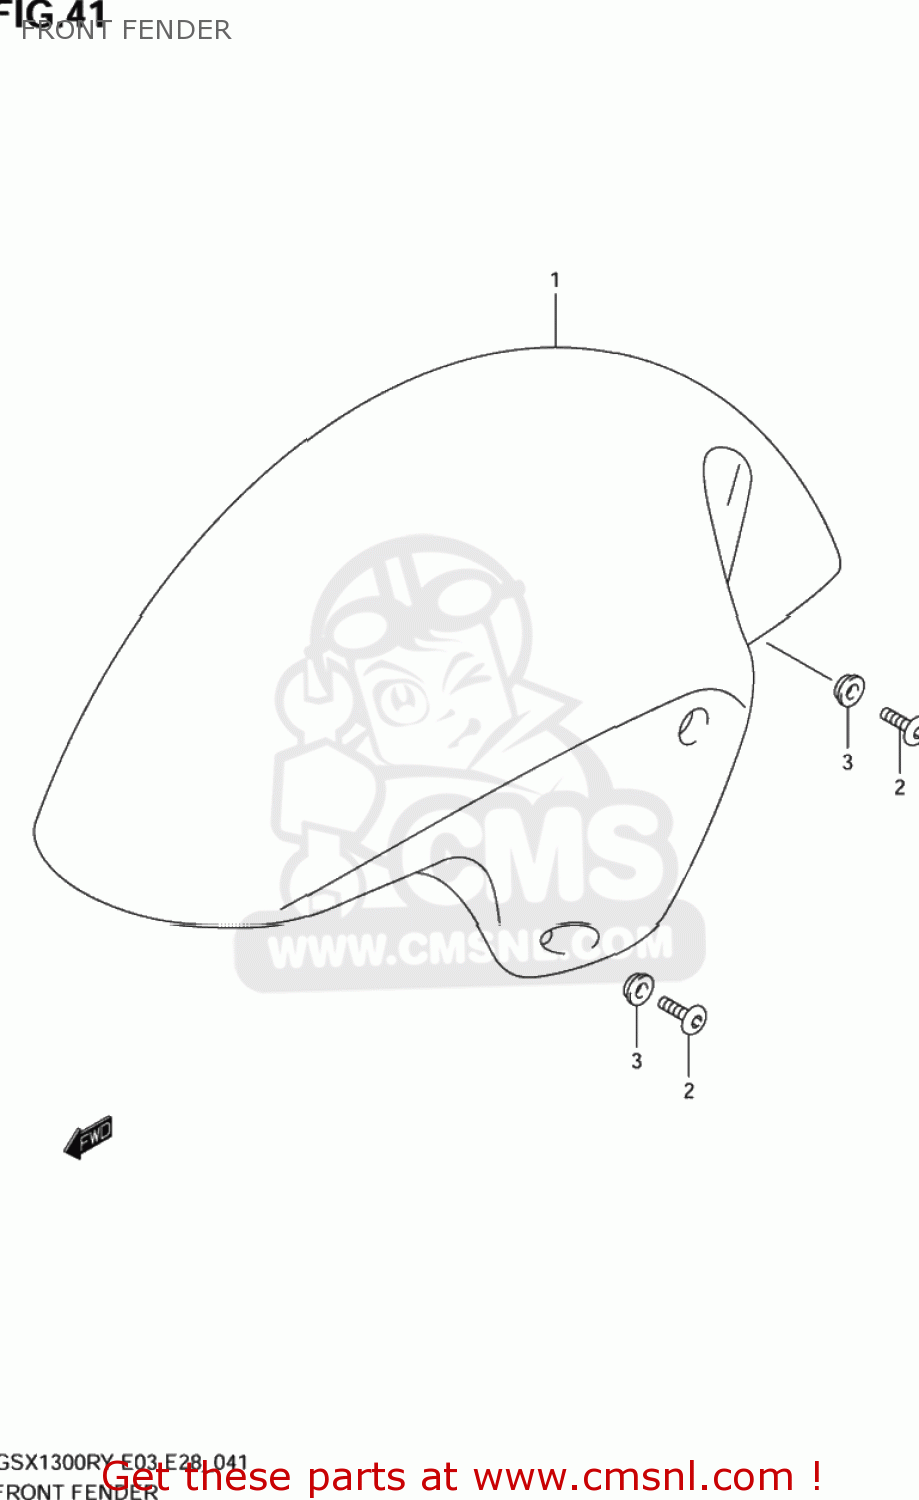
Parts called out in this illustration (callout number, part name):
1	FENDER,FR
2	SCREW(6X16)
3	WASHER(6.3X16X1.5)
